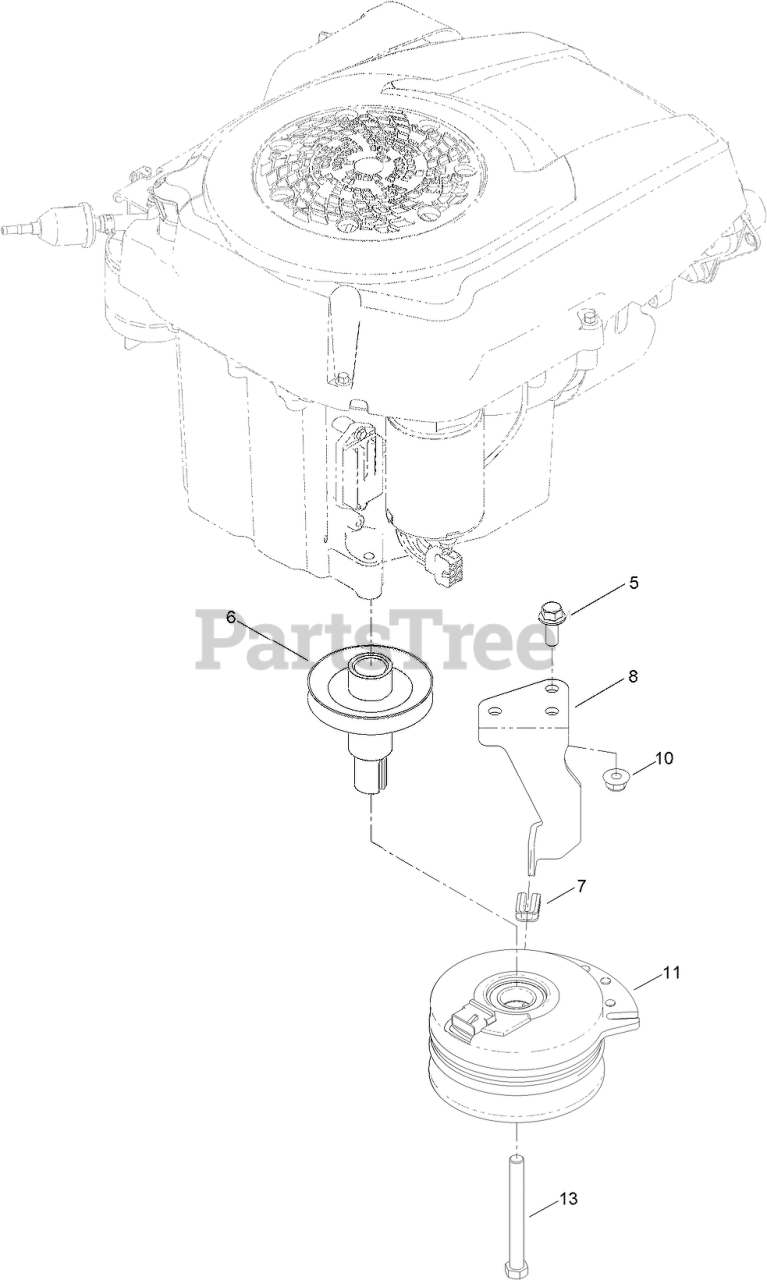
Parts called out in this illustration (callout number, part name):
5	SCREW-HHF
6	PULLEY-ENGINE
7	ISOLATOR-CLUTCH
8	STOP-CLUTCH
10	NUT-HF, NI
11	CLUTCH-ELECTRIC
13	SCREW-HH
